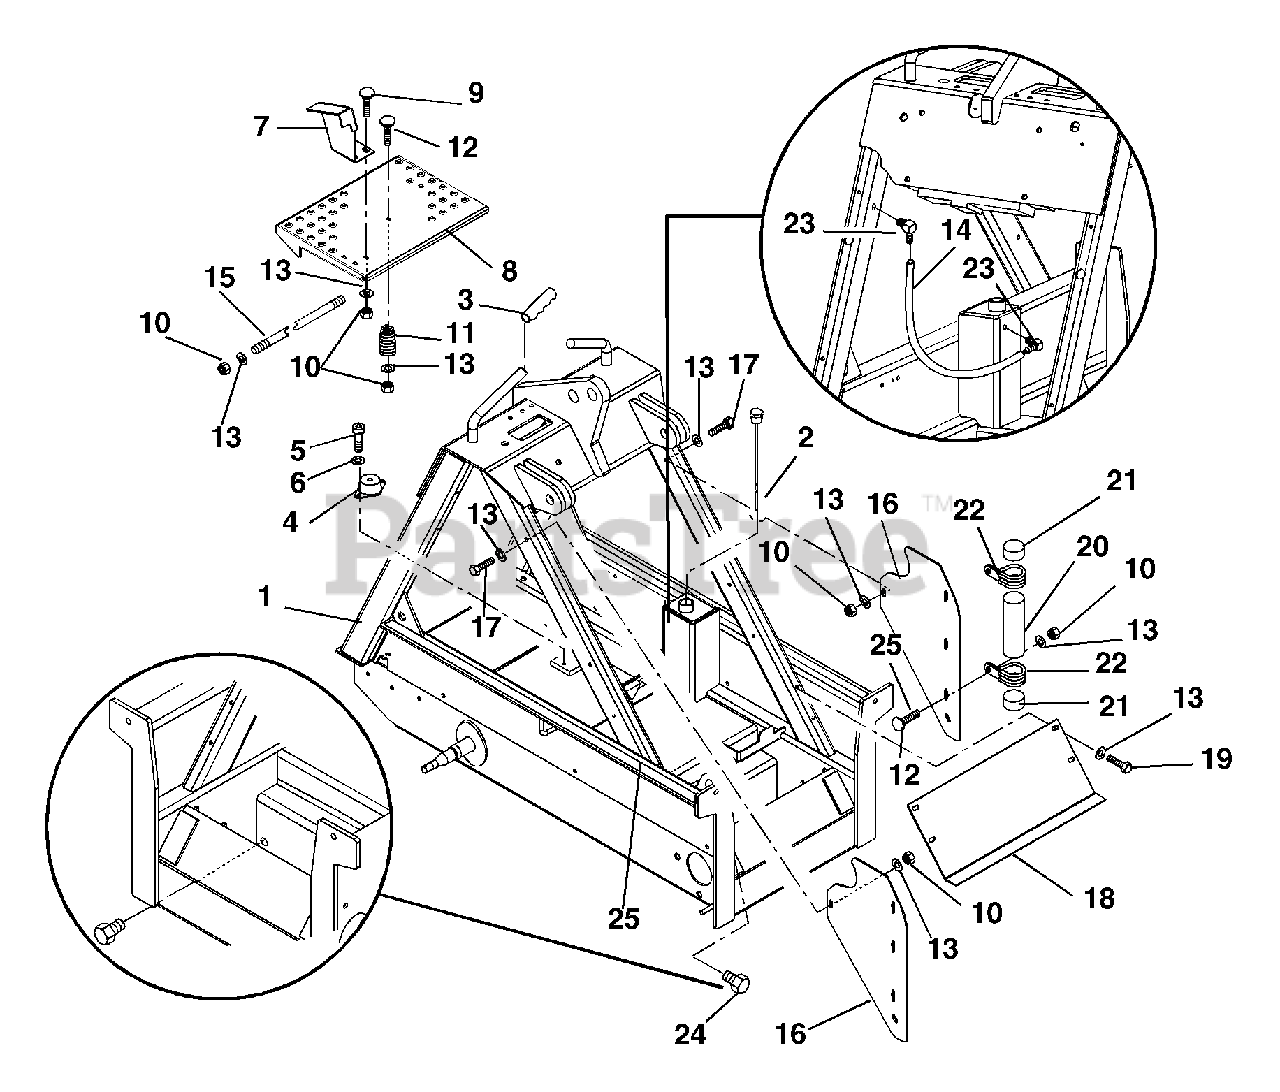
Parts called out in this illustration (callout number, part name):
2	Dipstick
3	Grip-Handle
4	Mount-Engine
5	Screw-Socket Head M8-1.25 x 12
6	Washer-Lock .31 x .078
7	Bracket-Hydraulic Stop
8	Grate-Floor Weldment
9	Bolt-Round Head Square Neck M8-1.25 x 20
10	Nut-Hex Locking Flange M8-1.25
11	Spring-Compression
12	Bolt-Round Head Square Neck M8-1.25 x 25
13	Washer-Flat-Steel .344 x .688 x .065
14	Line-Gas
15	Rod-Pivot
16	Guard-Pinch
17	Bolt, Hex M8-1.25 x 60
18	Plate-Inspection
19	Bolt-Hex M8 x 1.25 x 16
20	Tube-Instruction
21	End-Cap Instruction Tube
22	Clamp-2.00 Diameter with .406 Hole
23	Fitting-Barbed 90 Degree Elbow .125-27M x .25 I.D. Hose
24	Plug, Drain .75-14
25	Gasket-Foam with Adhesive Back 1" x 50' x .25"
